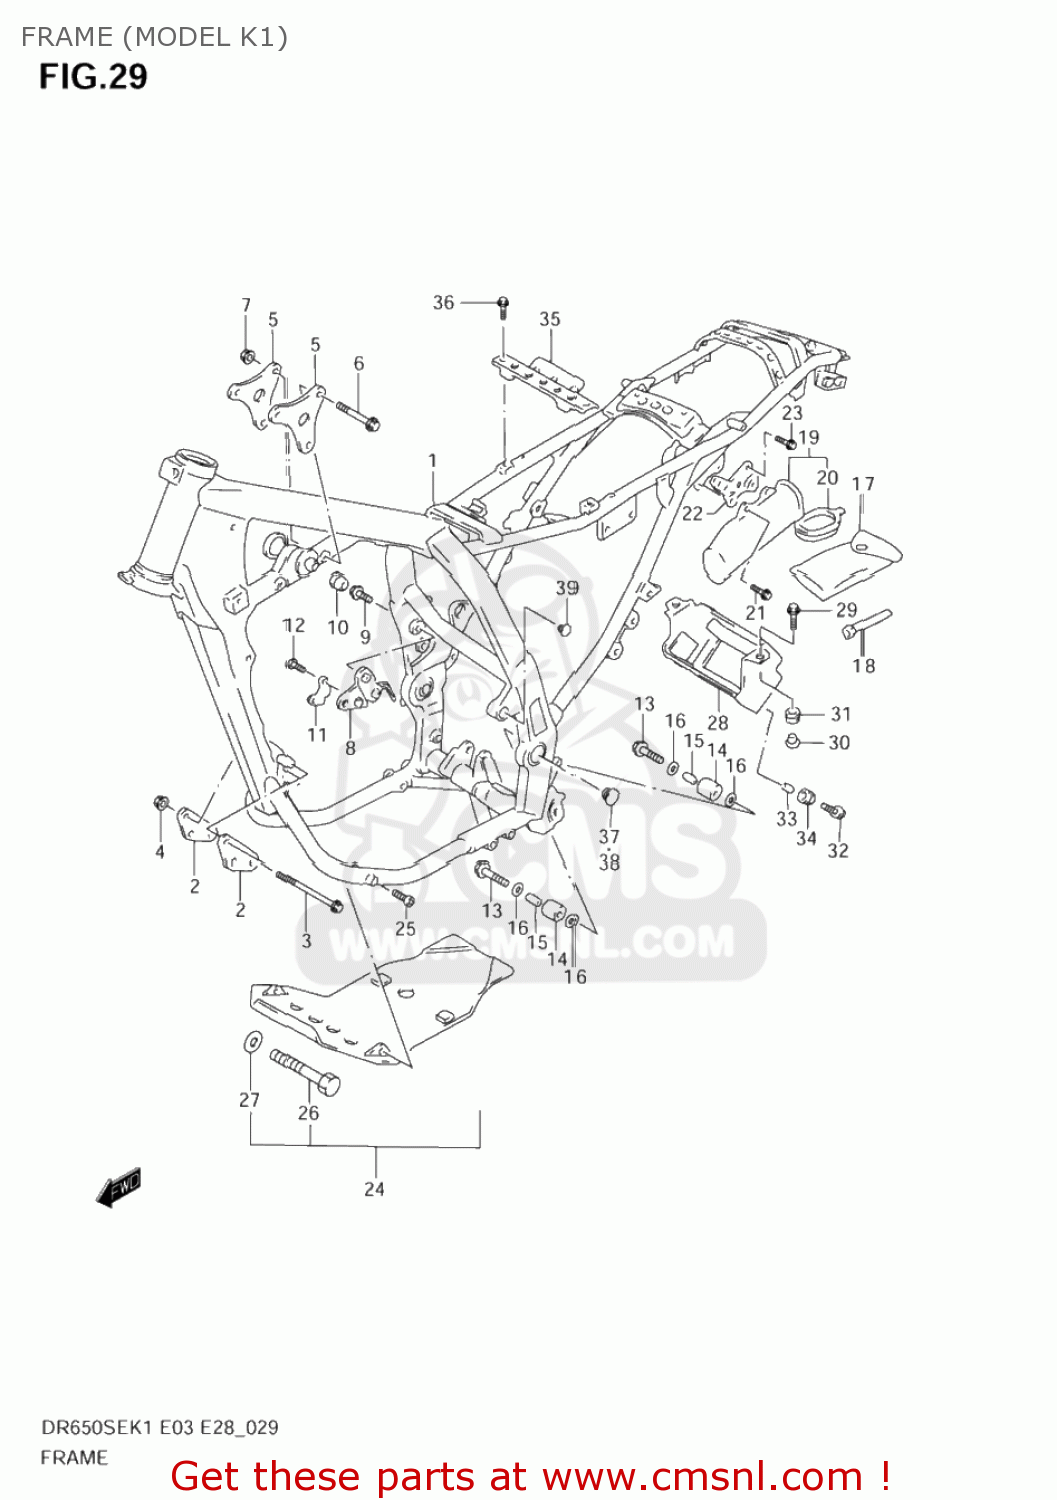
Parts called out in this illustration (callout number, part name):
1	FRAME(CHARCOAL)
2	PLATE,ENG MTG FR
3	BOLT(8X100)
4	NUT
5	PLATE,ENG MTG UPR
6	BOLT
7	NUT
8	PLATE,ENG MTG RR,R
9	BOLT
10	PLUG(OD:22)
11	BRACKET,STOP SWITCH
12	SCREW
13	BOLT(8X38)
14	ROLLER,CHAIN CONTROL UPR
15	SPACER(8.6X12X25.5)
16	WASHER
17	TOOL ASSY
18	SPARK PLUG WRENCH(16)
19	HOLDER,TOOL
20	CAP,HOLDER
21	BOLT(6X16)
22	BRACKET,TOOL HOLDER
23	BOLT
24	Skid Plate
25	BOLT(8X14)
26	BOLT(10X245)
27	WASHER(10X24X2)
28	HOLDER,BATTERY
29	BOLT(6X20)
30	WASHER
31	CUSHION
32	BOLT(6X16)
33	SPACER(6.1X9X7.5)
34	CUSHION
35	PLATE,BATTERY FITING
36	BOLT
37	PLUG,FRAME PIVOR,R
38	PLUG,FRAME PIVOR,L
39	PLUG,FRAME BOSS
